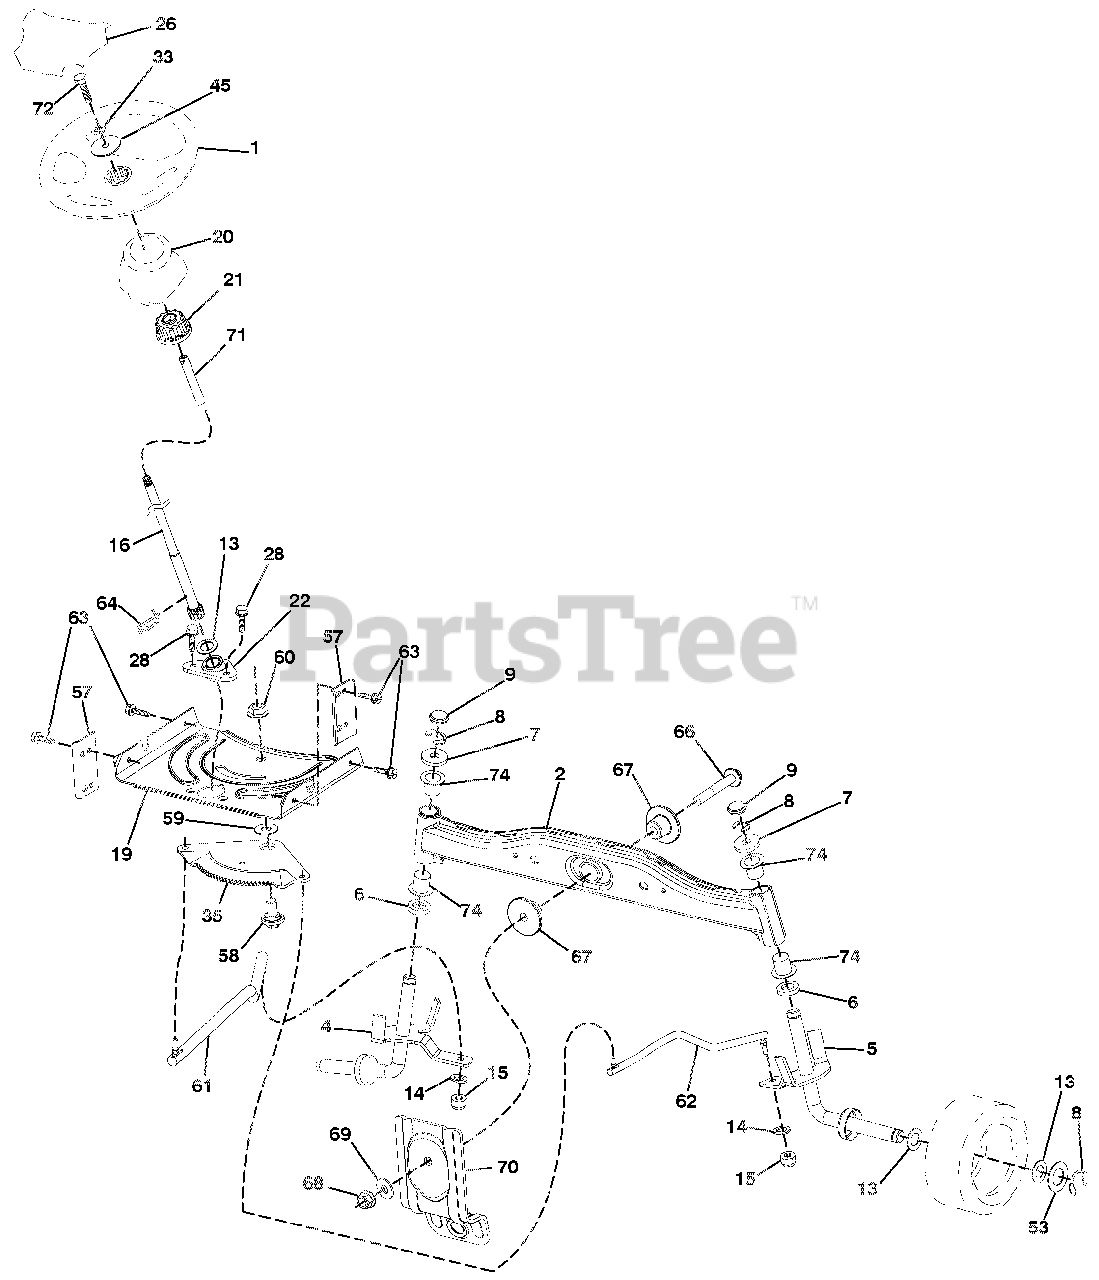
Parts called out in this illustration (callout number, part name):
1	WHEEL STEERING
2	AXLE ASM.WELDED
4	SPINDLE.WELDED.LH.15"TEX
5	SPINDLE.WELDED.RH.15"TEX
6	WASHER.THRUST..75 X 1.230
7	WASHER.25/32 X 1-5/8 X 16GA.
8	RING.KLIP.#T5304-75
9	CAP.SPINDLE.FR.TOP.BLK.
13	WASHER.25/32 X 1 1/4 X 16 GA.
14	Washer, Lock 3/8
15	NUT.CROWNLOCK.3/8-24
16	SHAFT.STEER.3/4 TEX.NON-PLATED
19	PLATE.STEER.DDL.NLT/NGT
20	BOOT.STEERING.LT.TEX P/L.428
21	ADAPTER.WHEEL.STRG..760
22	STEERING SUPT. LOWER
26	CAP.WHL.STRG.HRS/SRS.BLACK
28	SCREW.HEXWSH THDR3/8-16X3/4.BL
33	Washer, Lock 5/16
35	GEAR SECTOR.PLATE.DDL.NLT/NGT
45	WASHER.11/32ID X2 3/8OD X 12GA
51	NUT.HEX.JAM.TOPLOCK.1/2-20 UNF
53	WASHER.HARDEN..793 X 1.637X060
57	BRACKET.UPSTOP.TEX
58	BOLT.SHOULDER.SECTOR.PIVOT.CFM
59	WASHER.THRUST.SECTOR.STEER.NLT
60	NUT.FLANGE LOCK.5/8-11
61	DRAGLINK.LH.BALLSTUD.DDL.
62	DRAGLINK.RH.BALLSTUD.DDL
63	SCREW.5/16-18X3/4.SMGML.TAP/BL
64	RETAINER.CLIP.SPRING.STEERING
66	BOLT.HEX.FGHD.7/16-14 X 3.SERR
67	BUSHING.PM.FRONT AXLE
68	NUT.LOCK.FLANGE.7/16-14.GR5
69	WASHER.1.5 X .505 X .118
70	BRACKET.DECK.SUSPENSION.FRONT
71	Extension Steering
72	Bolt 5/16-18 x 14 w/Patch
74	BEARING.COL.STRG.BLK.
